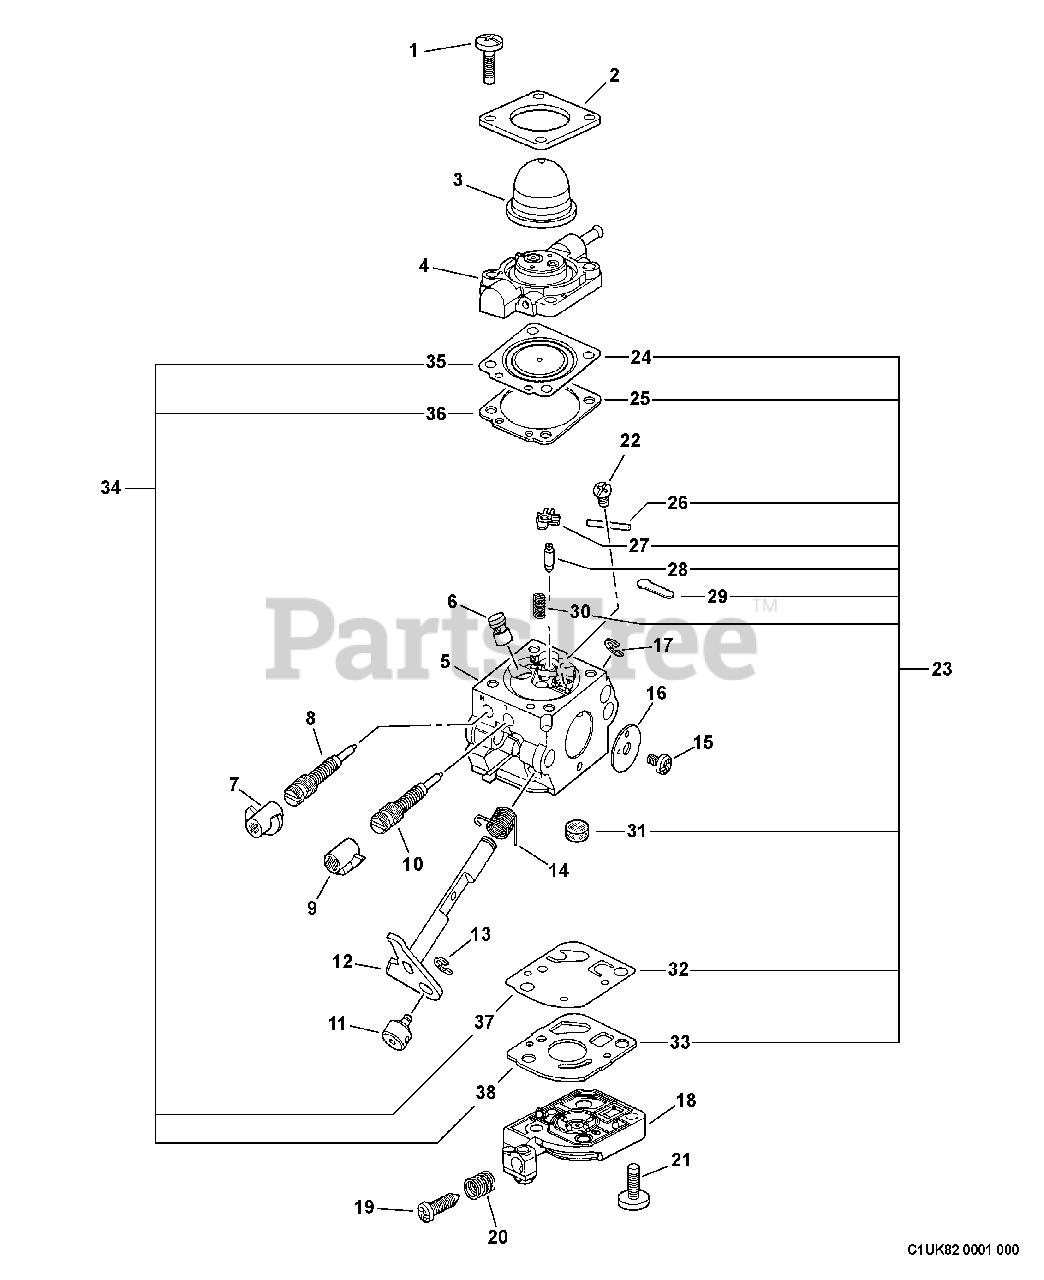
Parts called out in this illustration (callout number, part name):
2	RETAINER, PURGE BULB
3	BULB, PURGE
4	BODY ASSY, PURGE
5	BODY, CARBURETOR
6	NOZZLE, CHECK VALVE
7	CAP, LIMITER - RED
8	NEEDLE, HIGH SPEED
9	CAP, LIMITER - WHITE
10	NEEDLE, MIXTURE
12	SHAFT ASSY, THROTTLE
14	SPRING, THROTTLE RETURN
16	VALVE, THROTTLE
18	COVER, FUEL PUMP
19	SCREW, THROTTLE ADJUST
23	REBUILD KIT
24	DIAPHRAGM, METERING
25	GASKET, METERING
26	PIN, METERING LEVER
27	LEVER, METERING
28	VALVE, INLET NEEDLE
29	PLUG, WELCH
30	SPRING, METERING LEVER
31	STRAINER
32	DIAPHRAGM, PUMP
33	GASKET, PUMP
34	GASKET / DIAPHRAGM KIT
35	DIAPHRAGM, METERING
36	GASKET, METERING
37	DIAPHRAGM, PUMP
38	GASKET, PUMP
